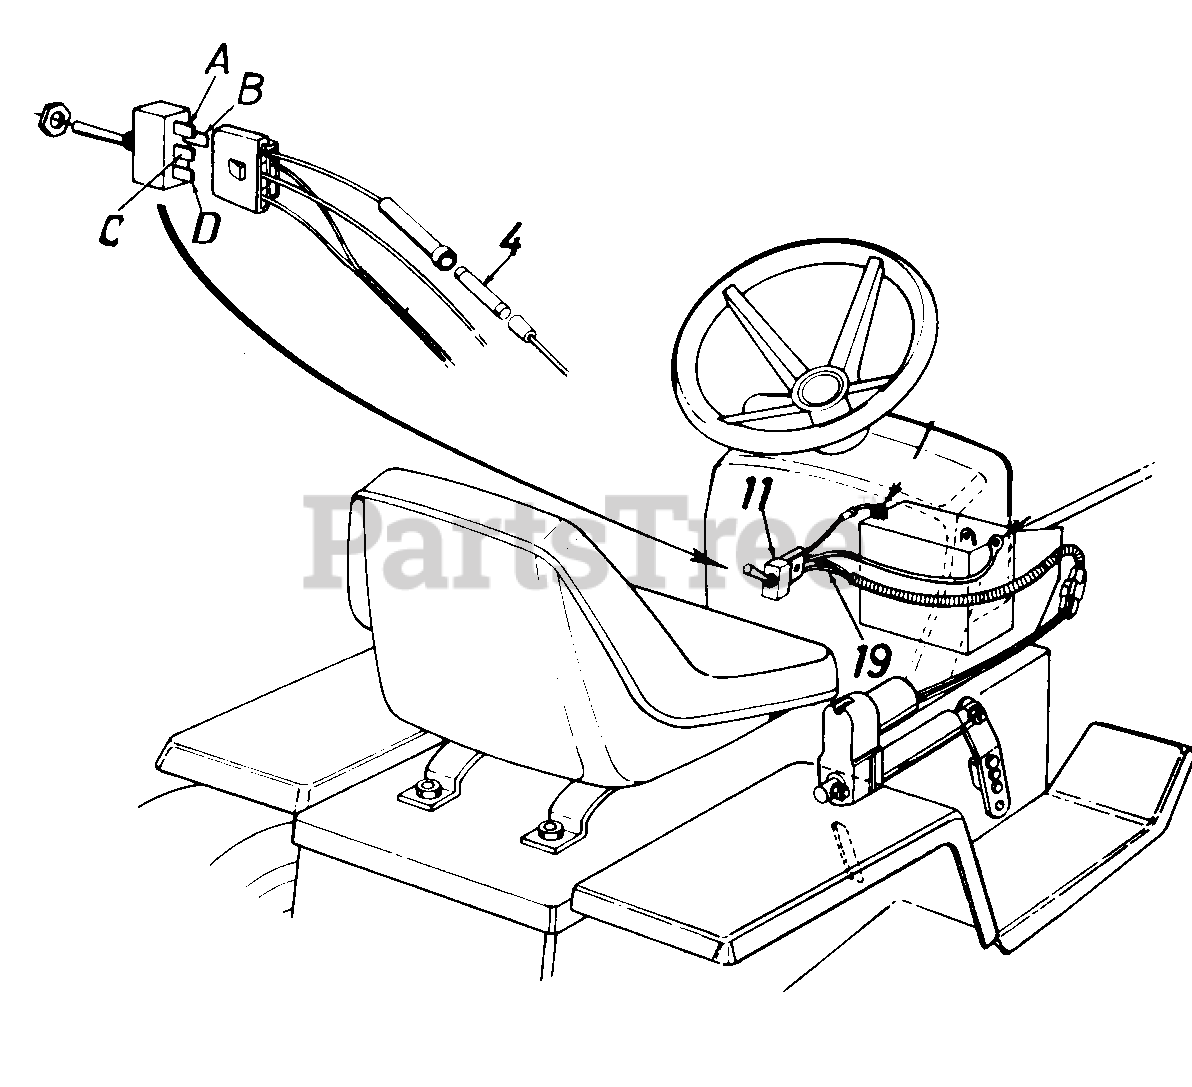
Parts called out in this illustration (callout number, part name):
4	Fuse 30 AMP
11	Toggle Switch
19	Wire Harness
A	Connects to Positive Terminal on Battery
B	Connects to Actuator
C	Ground Wire to Frame
D	Connects to Actuator
